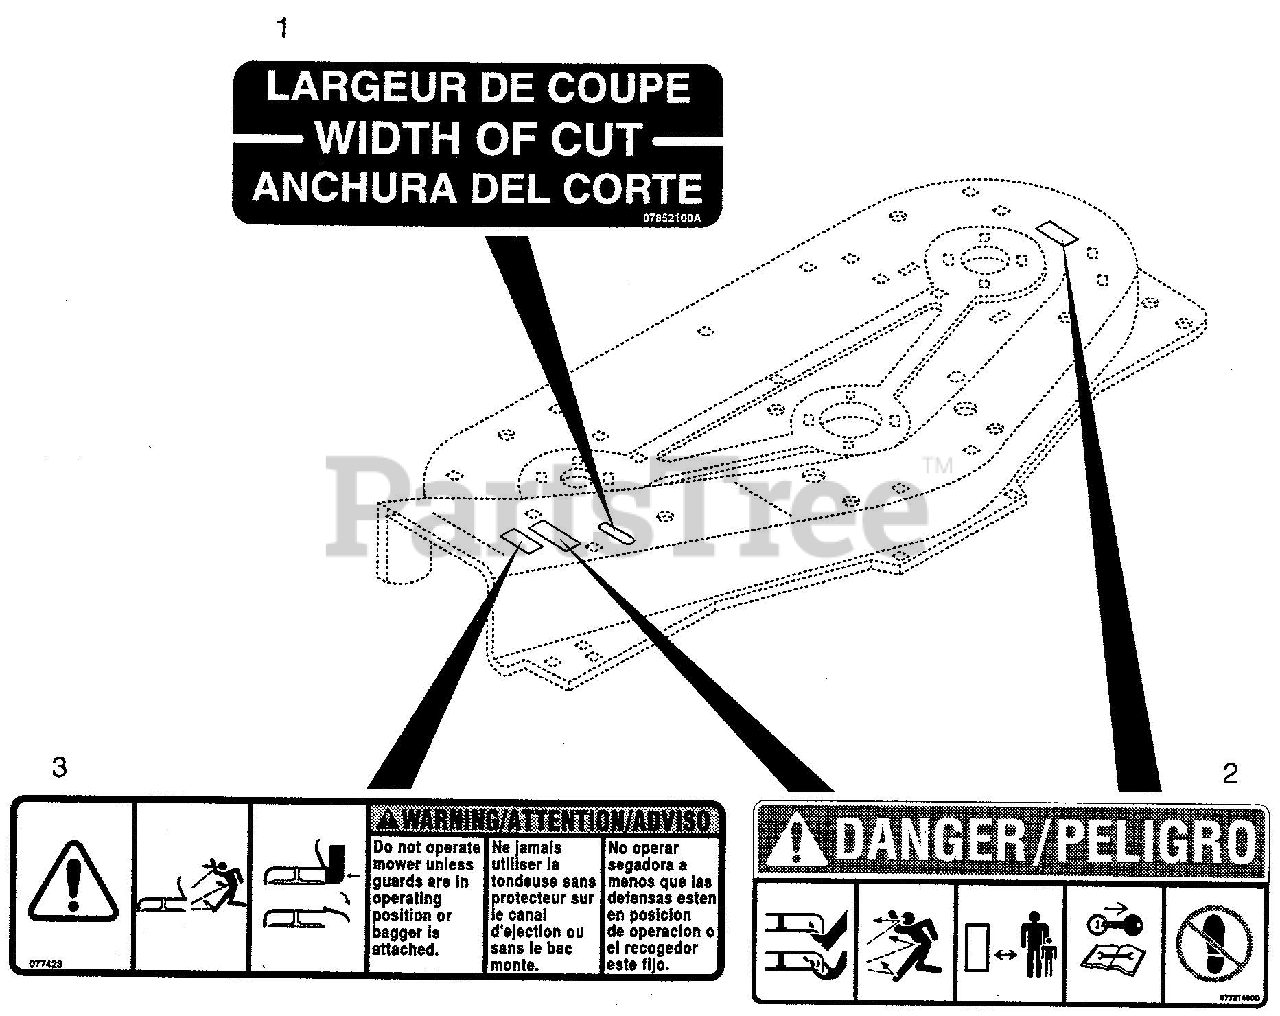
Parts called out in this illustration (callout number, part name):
1	DECAL, WIDTH OF CUT
2	DECAL, MOWER PAN HEAD DANGER
3	DECAL, WARNING
